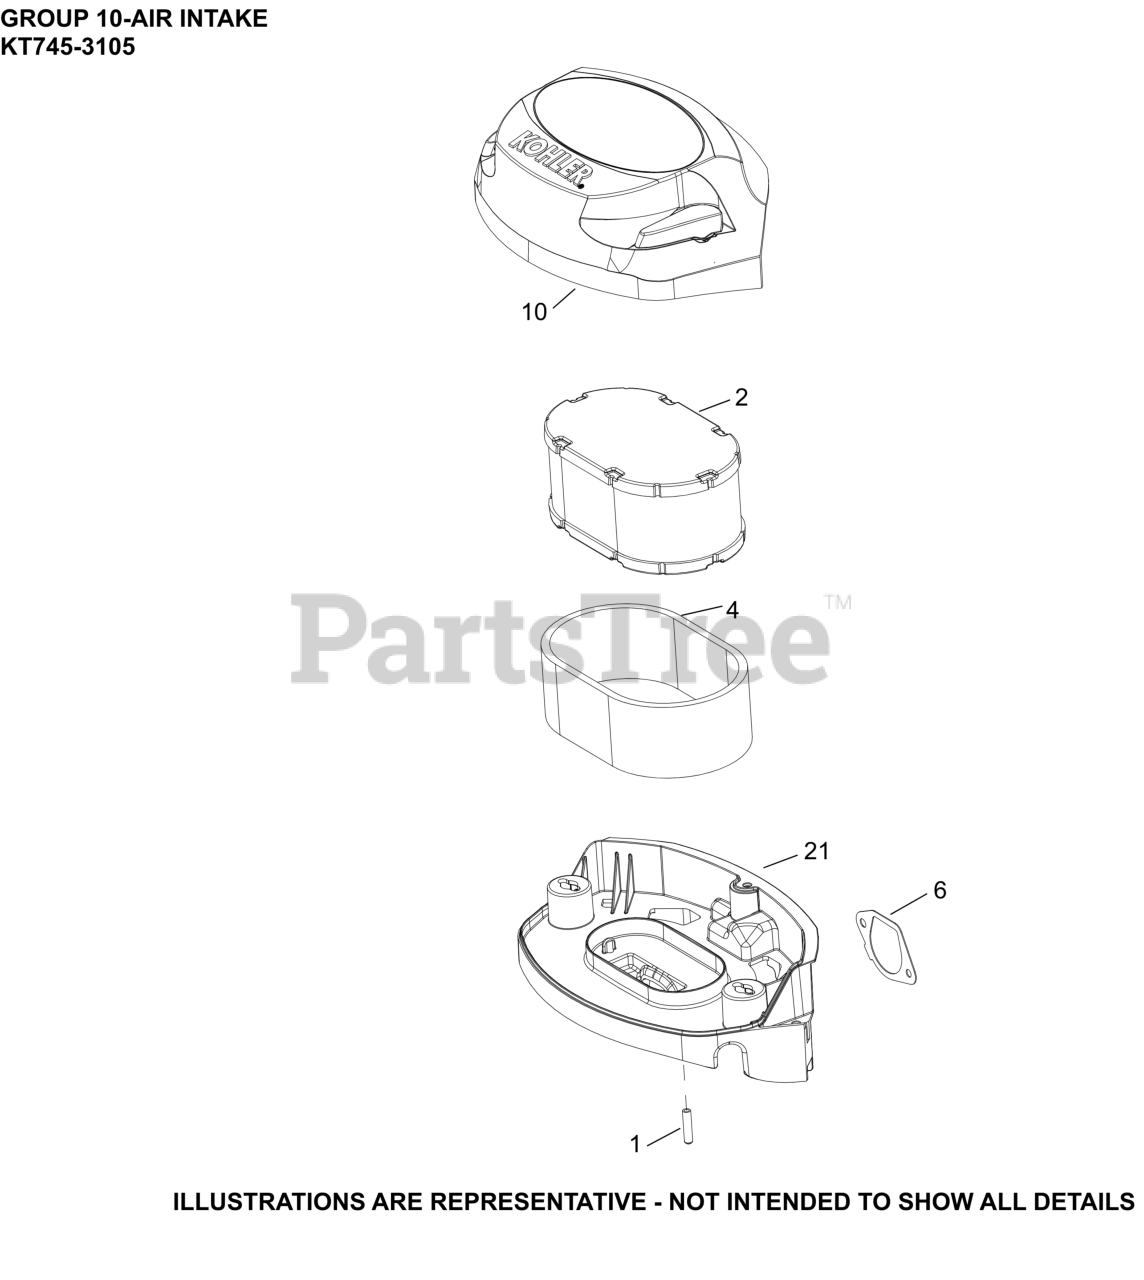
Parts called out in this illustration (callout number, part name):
1	CAP, MASKING
2	ELEMENT, AIR FILTER
4	ELEMENT, PRE-CLEANER
6	GASKET, AIR CLEANER BASE
10	COVER ASSY, AIR CLEANER
21	BASE ASSEMBLY, AIR CLEANER
